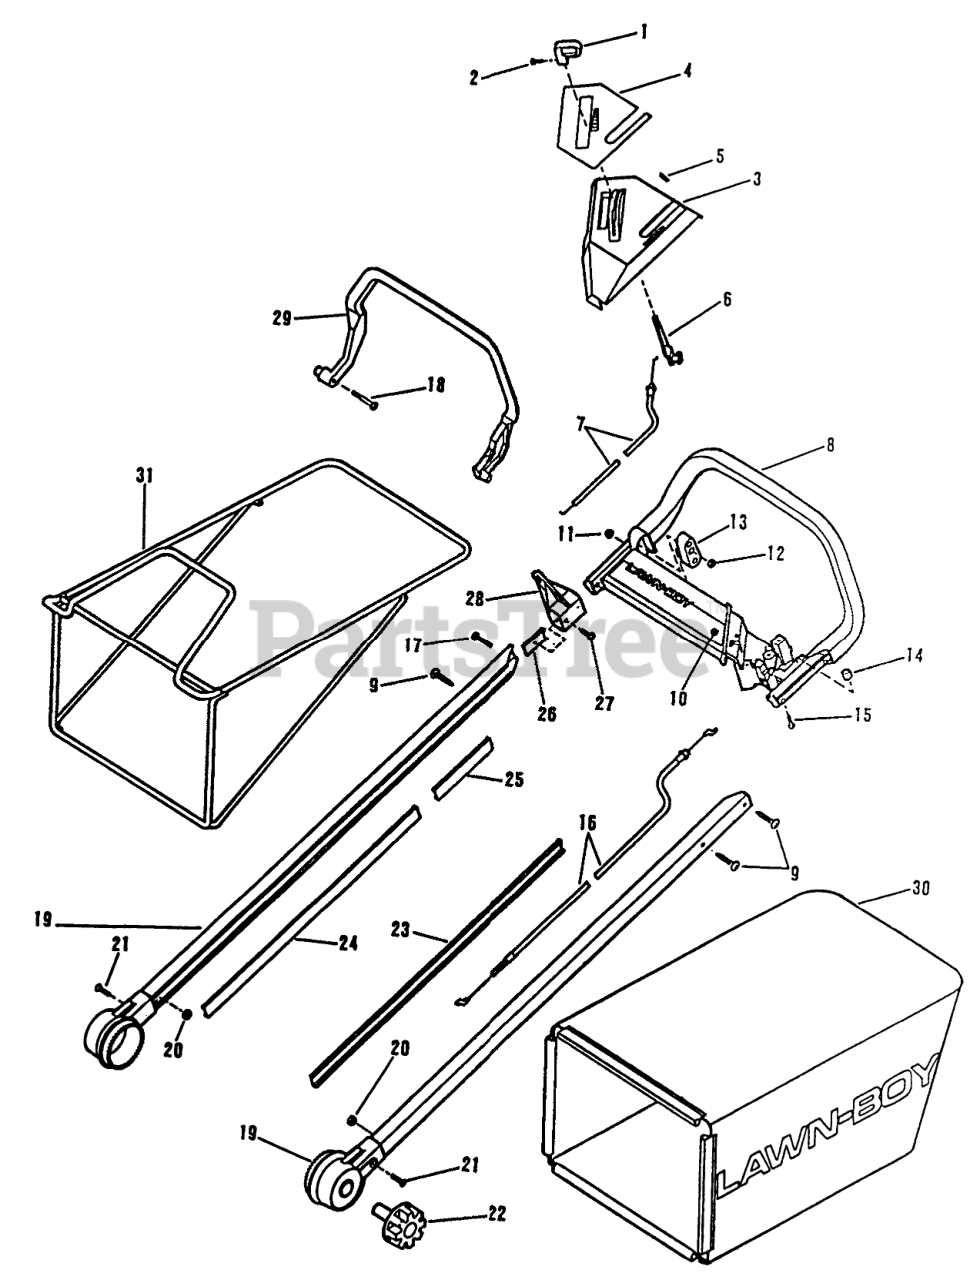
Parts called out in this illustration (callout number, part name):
1	KNOB & SCREW AY
2	SCREW-SELF TAP
3	UPPER CVR W/DECAL
4	Plate
5	PLUG - BUTTON
6	LVR ASSM THROTTLE LB
7	CABLE
8	HANDLE & DECAL AY.
9	SCREW
10	DECAL - LAWNBOY
11	LOCKNUT FLAN
12	LOCKNUT E
13	BLOCK BAIL PL
14	BUMPER
15	SCREW - TRUSS HEAD
16	CABLE ASSEMBLY
17	SCREW-TRUSS
18	SCREW - TRUSS HEAD
19	Handle Shaft Assembly
20	LOCKNUT FLAN
21	SCREW
22	KNOB-HDLE MT.ASMB
23	Handle Insert-Cable Side
24	Handle Insert-Below Guide
25	INSERT - HANDLE
26	NUT LB
27	SCREW
28	ROPE GUIDE AY
29	Blade Brake Bail
30	REPL BAG FOR 684190
31	FRAME AY-GRASS BAGB
